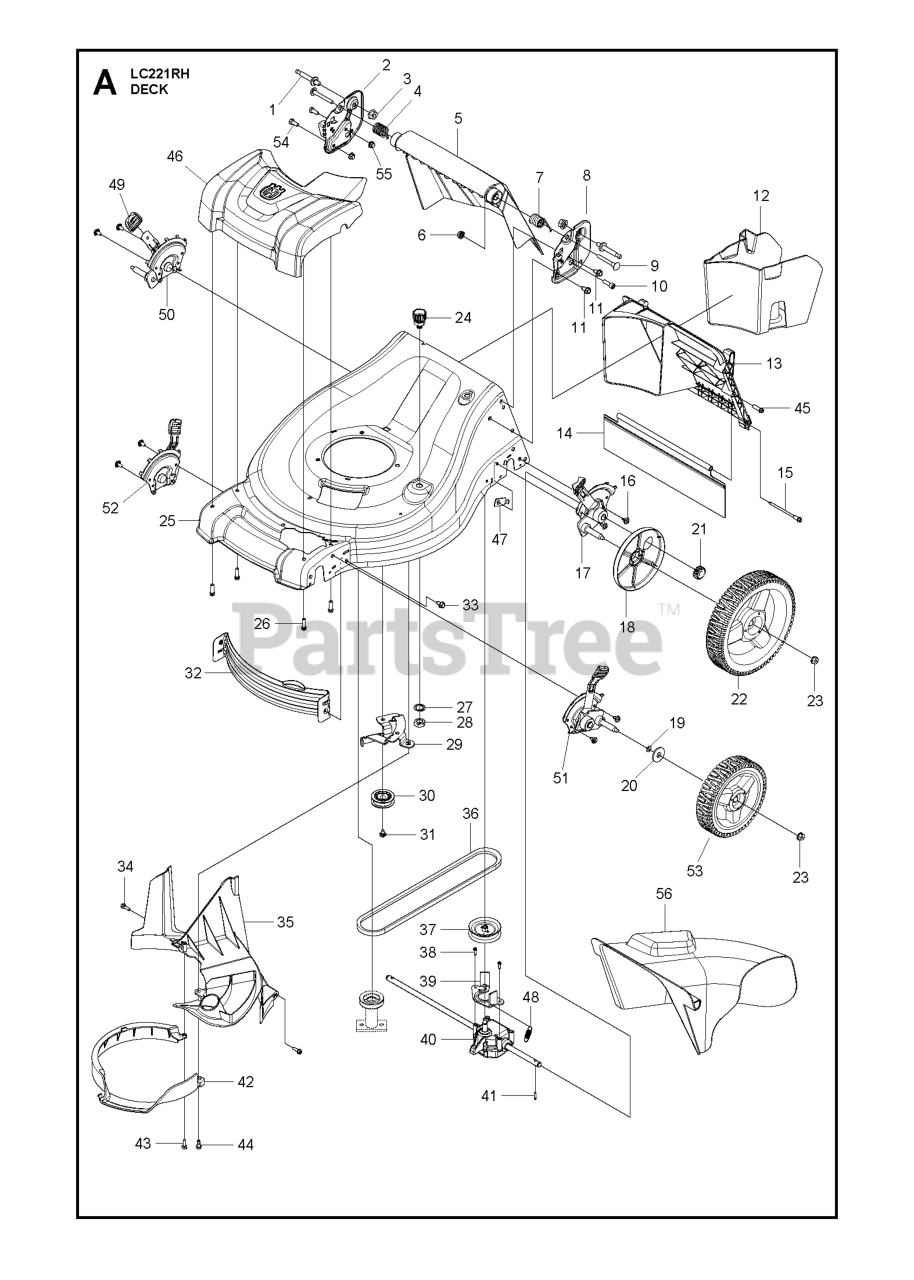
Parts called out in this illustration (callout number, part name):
1	BOLT.HAND.PIVOT.3125-18.21EFF
2	BRACKET.HANDLE.ADJ.21EF.RH.498
3	NUT.FLANGE.SERRAT.3125-18.5625
4	SPRING.RH.DOOR.21 EFF
5	DOOR.REAR.21 EFF.GRY
6	NUT.FLANGED.3/8-16.ZINC
7	SPRING.LH.DOOR.21 EFF
8	BRACKET.HANDLE.ADJ.21EF.LH.498
9	BOLT.DOOR.PIVOT..375-16.21EFF
10	SCREW.HI-LO,5/16-14 X T-45
11	BOLT.5/16HEX.WHS.HD
12	PLUG.MULCH.21 EFF
13	INSERT.REAR.21 EFF
14	SKIRT.REAR.21 EFF
15	SCREW.HI-LO.5/16-14 X 4.10
16	SCREW
17	ADJUSTER.4PT.21EFF.LR.HW.BK
18	COVER.DUST.WHEEL.HW.AWD.REAR
19	O-RING..070X.487.NEOPRENE
20	WASHER FLUT
21	PINION.16.TEETH.HW.AWD.REAR
22	WHEEL.11.H3SP.RWD.LC.460.BB2
23	NUT.HEX.FLANGE.3/8-16.LO(3 2)
24	FITTING, HOSE, WATER WASHOUT
25	KIT.HSG.21EFF.AWD.WO.668.CE SY
26	SCREW.HI-LO. 5/16 X 1.00
27	WASHER.LOCK.INTERNAL.TOOTH
28	LOCKNUT.HEX.WITH.O-RING
29	BRACKET.IDLER.RWD.BZP
30	PULLEY.RWD.IDLER.DBL SEAL
31	SCREW
32	BAFFLE.FRONT.21 EFF
33	BOLT.5/16HEX.WHS.HD
34	SCREW.HI-LO.13-16X.750.375XDRV
35	COVER.BELT/REAR BAFFLE.21 EFF
36	BELT.21EFF.RWD
37	PULLEY.DRIVE.SM.AWD/RWD
38	SCREW
39	BRACKET.TRANS.BELTKEEP.21 RWD
40	TRANSMISSION.AWD.REAR.21EFF
41	PAWL, DRIVE
42	RING.STRIPPER.21 EFF
43	SCREW.HI-LO.13-16X.750.375XDRV
44	BOLT SHOULDER_1/4-20_TRILOB
45	SCREW.HI-LO. 5/16 X 1.00
46	COVER.DR.FULL.HUSQ.21EFF.RWD
47	STRAP.PLATE ATTACH.21 EFF.GLV
48	SPRING.RETURN.AUTO.
49	SELECTOR KNOB
50	ADJUSTER.4PT.21EFF.RR.HW.BK
51	ADJUSTER.4PT.21EFF.LF/RR.BU.BK
52	ADJUSTER.4PT.21EFF.RF/LR.BU.BK
53	WHEEL & TIRES ASSY, FRONT
54	BOLT.FIN.HEX.5/16-18X3/4
55	NUTNYLOK.FLRANGE.5/16-18
56	CHUTE.DISCHARGE.21EFF.HW
